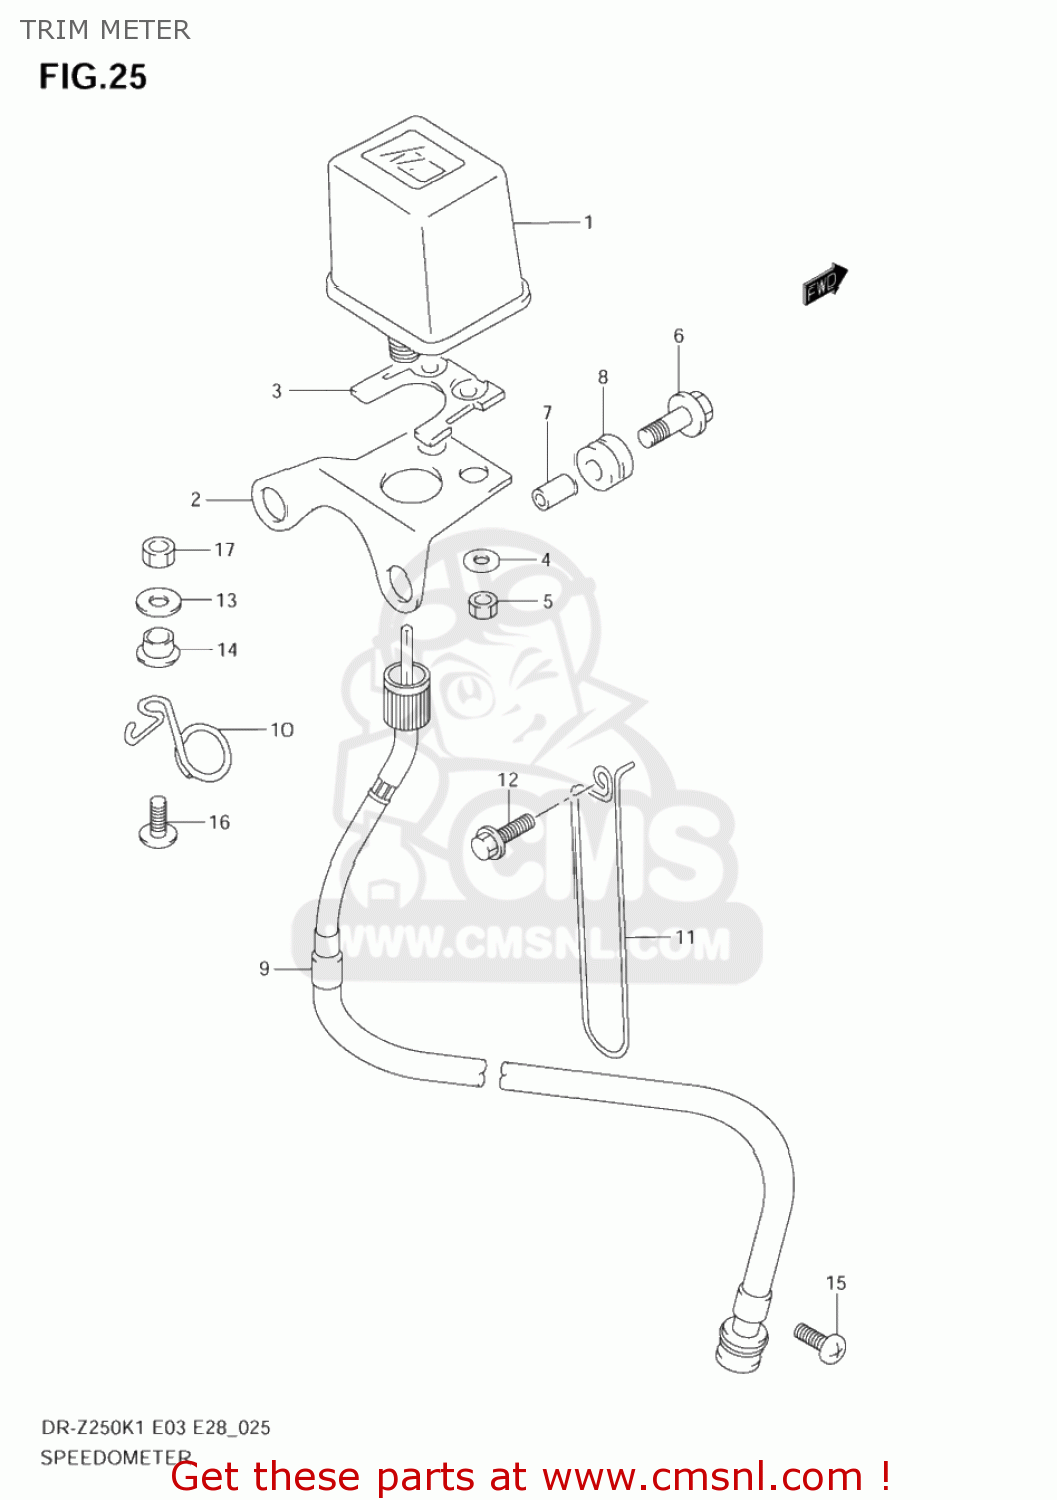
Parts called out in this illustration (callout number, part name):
1	TRIP METER
2	BRACKET
3	CUSHION
4	WASHER(4.3X14X0.8)
5	NUT
6	BOLT(6X25)
7	SPACER(6.1X8X9.5)
8	CUSHION
9	CABLE ASSEMBLY,SPEEDOMETER
10	GUIDE,SPEEDOMETER CABLE
11	GUIDE,METER CABLE NO.2
12	BOLT(6X16)
13	WASHER(6.5X18X1.6)
14	WASHER
15	SCREW
16	SCREW
17	NUT 6MM
